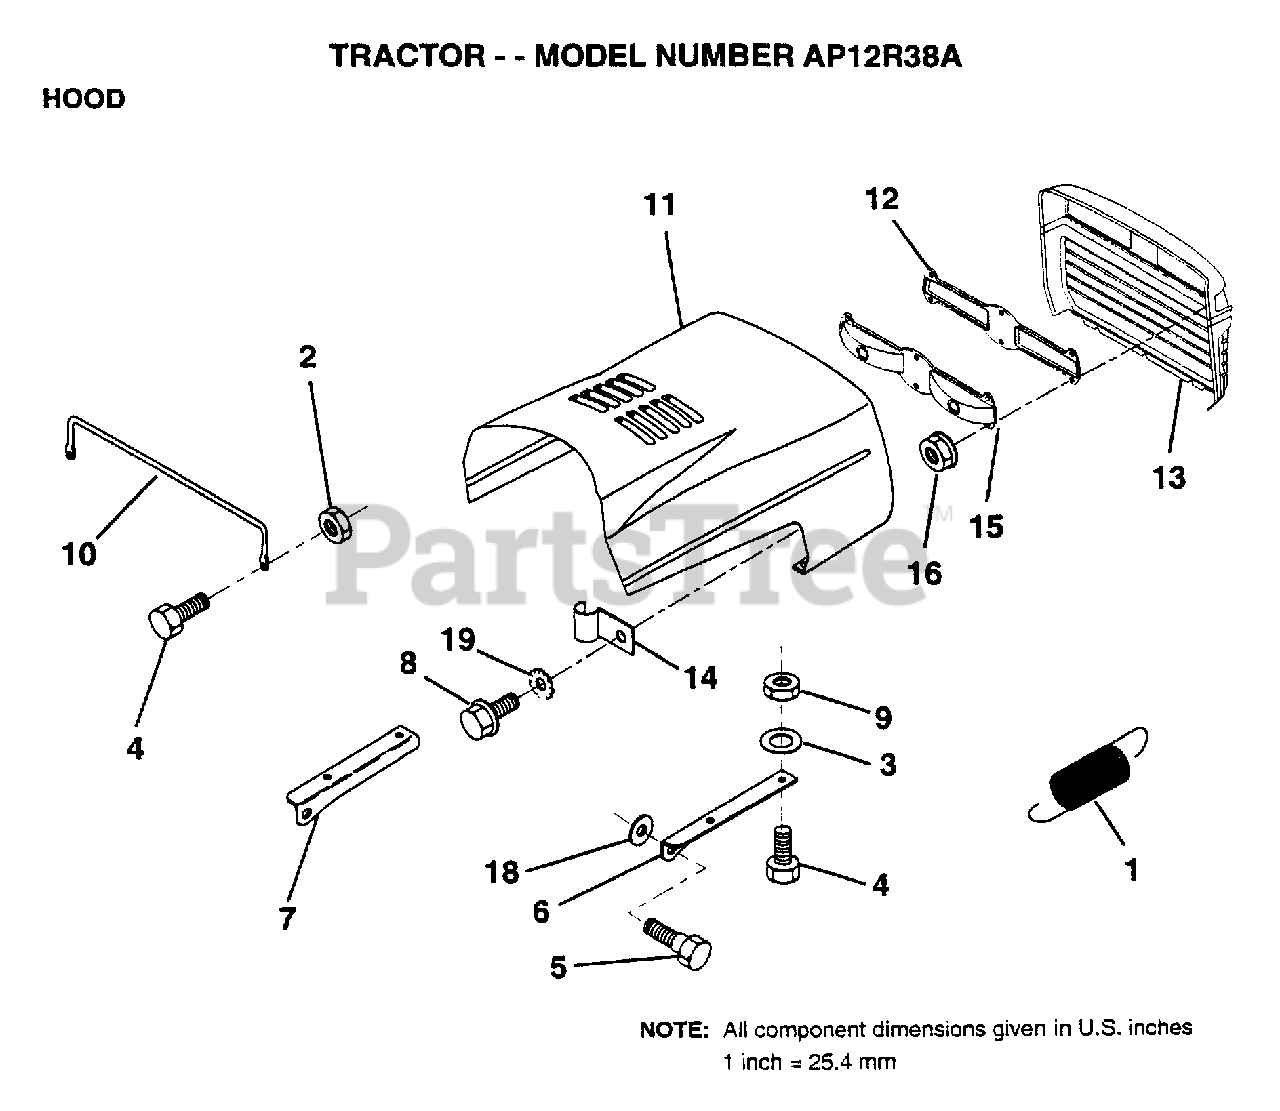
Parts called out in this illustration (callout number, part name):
1	EXT SPRING
2	NUT HXKEP 1/4X20
3	WASHER
5	BOLT.SHLD.5/16-18
6	BRKT HOOD RH
7	BRKT HOOD LH
8	SCREW SLTD HXHD
9	NUT
10	"BRACE,HOOD"
11	HOOD
13	GRILL (BLACK)
16	NUT
18	WASHER
19	LOCKWASHER GT
